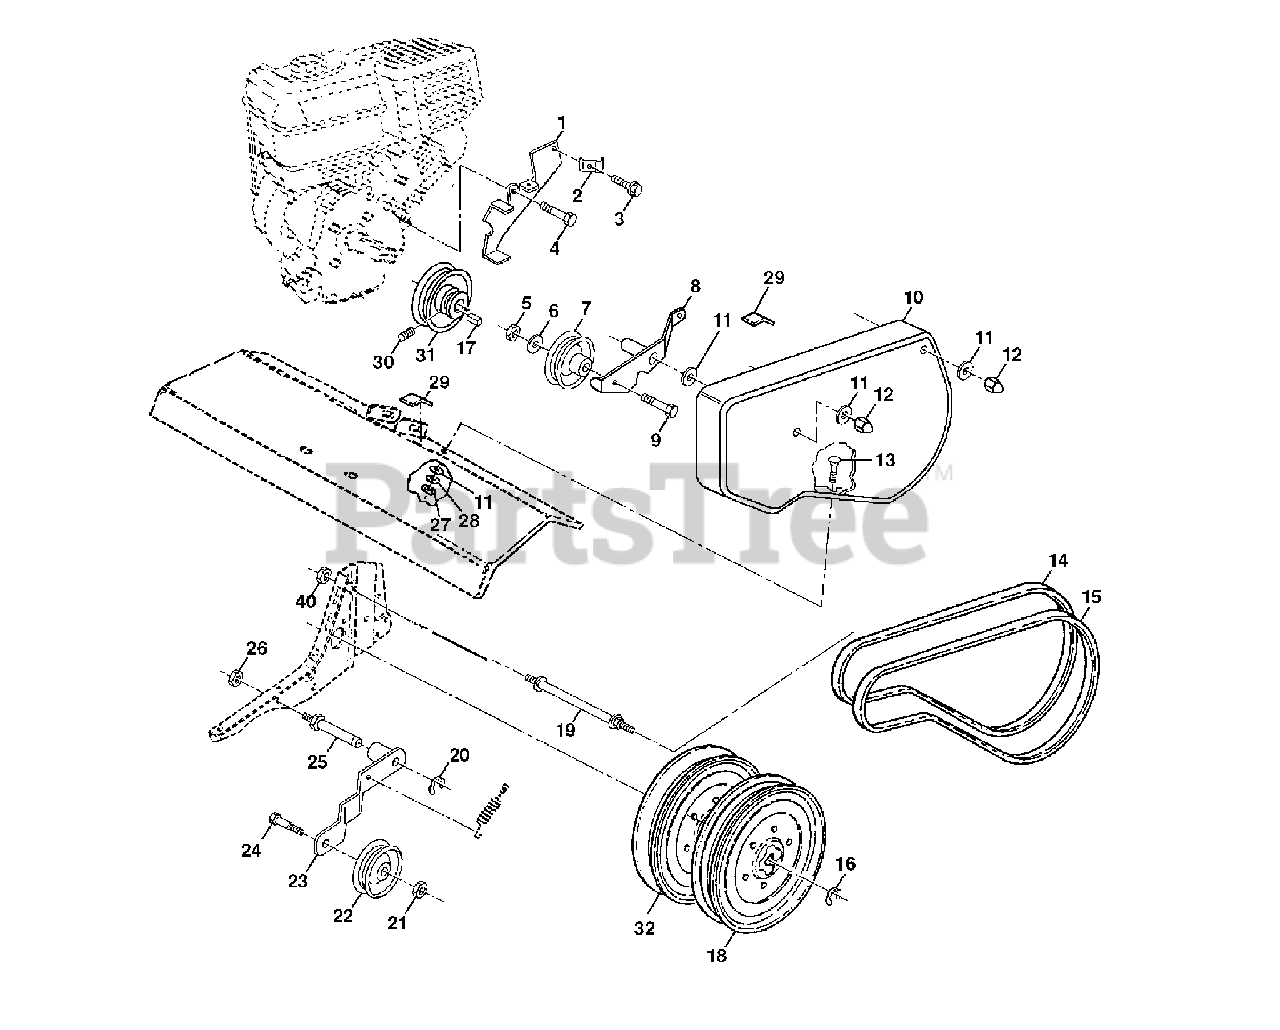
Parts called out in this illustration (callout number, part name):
1	Assembly, Bracket, Belt Guard
2	Clip, Cable
3	Screw, Hex, Washer Hd., Slotted, Thd. Cutting #10-24 x 1/2 Type D
4	Bolt, Hex 1/2-20 x 3/4
5	Nut, Hex 3/8-16
6	Washer 13/32 x 13/16 x 16 Ga.
7	Pulley, Idler, Reverse
8	Assembly, Arm, Reverse Idler
9	Bolt, Hex 3/8-16 x 1-3/4
10	Guard, Belt
11	Washer 9/32 x 5/8 x 16 Ga.
12	Nut, Cap 1/4- 20
13	Bolt, Carriage 1/4-20 x 3/4
14	V-Belt (Forward Motion)
15	V-Belt (Reverse)
16	Ring, Retainer
17	Key, Square
18	Pulley, Flat, Trans.
19	Bolt, Belt Guard
20	Ring, Klip
21	Nut, Hex, Jam 3/8-16
22	Pulley, Idler
24	Bolt, Hex 3/8-16 x 1-1/4
25	Shaft, Idler Arm
26	Nut, Hex, Jam 5/16-18
27	Nut, Fin Hex 1/4-20
28	Washer LK Hvy Helical 1/4
29	Pad, Idler
30	Screw, Set , Socket, Headless C.P. 1/4-20 x 1 /4
31	Sheave, Engine
32	Pulley, V-Groove, Trans.
35	Washer 9/32 x 7/8 x 16 Ga.
40	Nut Keps Hex 1/4-20
